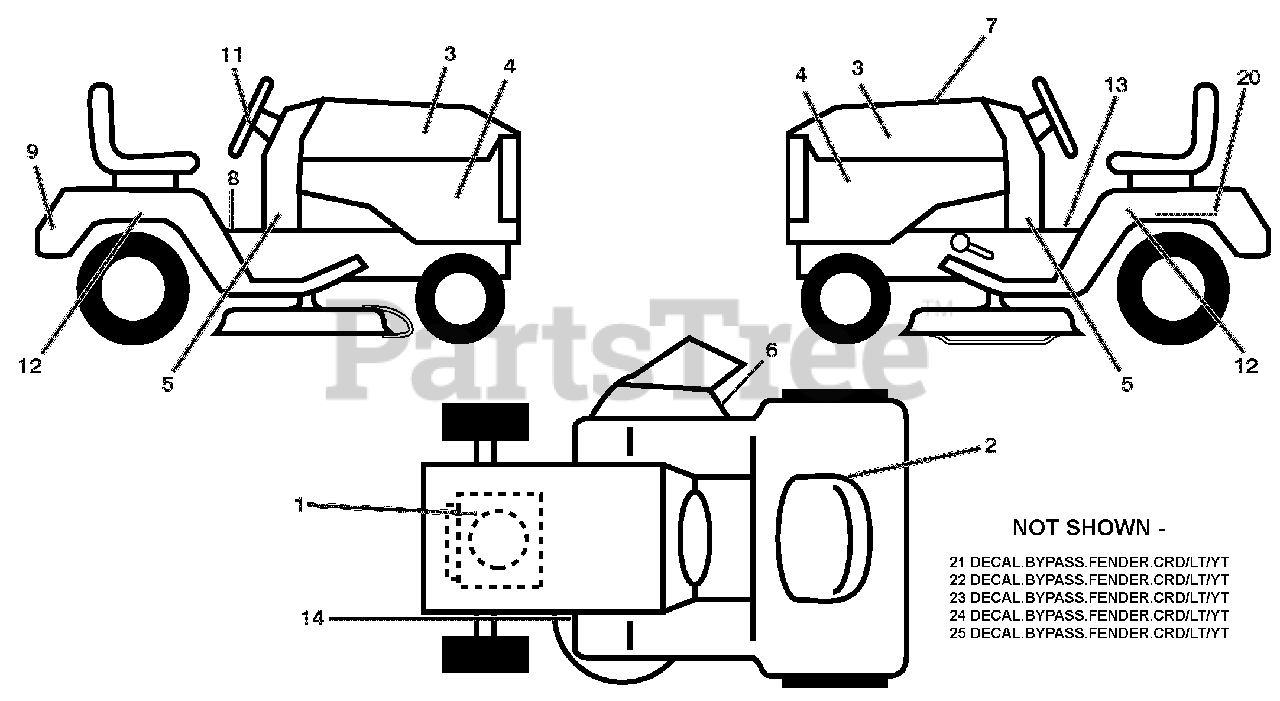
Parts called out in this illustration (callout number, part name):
1	DECAL ENGINE H.P.
2	Decal Fender Service
3	DECAL.HOOD.LH/RH.
4	DECAL.SDPNL.PWRDBY B&S.ARIENS
5	DECAL.DASH.LWOWER.20HP.ARIENS
6	DECAL.MOWER.WARN.KEEP HAND AWY
7	DECAL.REPLACEMENT
8	DECAL.FENDER.WARNING.ENG/FR.07
9	DECAL.FENDER.REAR.ARIENS
11	DECAL.WHEEL.STEER.ARIENS
12	DECAL.FENDER.SIDE.HYDRO.ARIENS
13	DECAL.FENDER
14	DECAL.V-BELT.SCH.42/46"MEC/ELE
20	DECAL.BAT.DAN/POI P/L SYM.WPN
